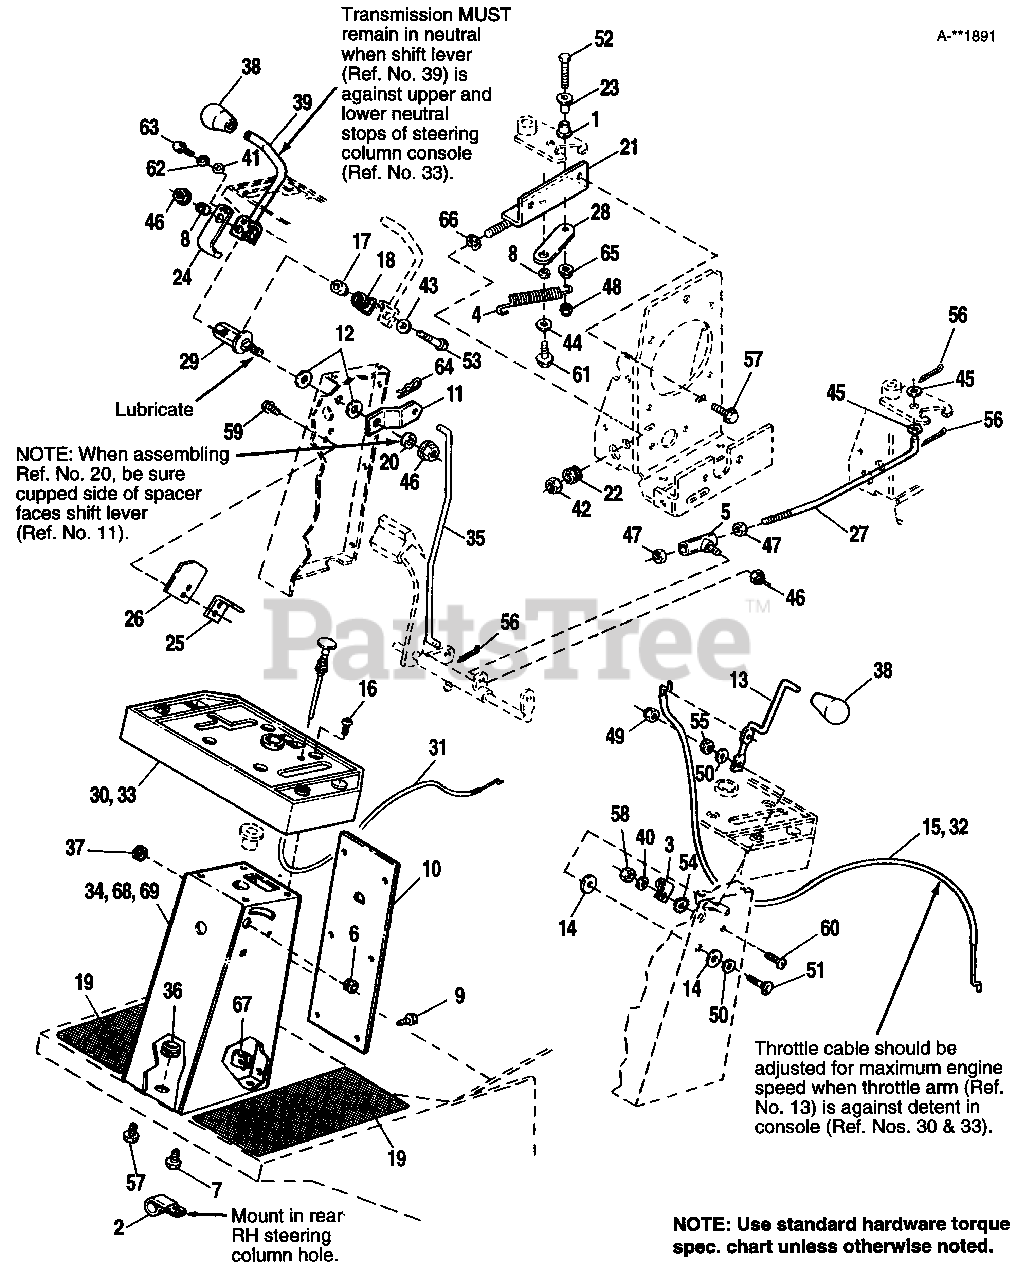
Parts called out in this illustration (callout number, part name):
1	BUSHING, Nylon
4	SPRING, Extension
7	SCREW, Taptite, 5/16-18 x 3/4
9	SCREW, Hex, 1/4-14 x 5/8
10	PANEL, Steering Column
11	LEVER, Shift
12	WASHER, Nylon, 33/64 x 1
13	THROTTLE ARM
14	WASHER, Nylon
15	CABLE, Throttle (12 HP)
16	SCREW, Taptite, 1/4-20 x 3/4
18	SPRING, Torsion
21	BRACKET ASSY., Control
22	NUT, Adjusting
24	NEUTRAL SWITCH ARM
25	BRACKET, Switch
26	FLIPPER SWITCH (Plastic)
27	ROD, Control
28	ARM, Control
29	PIVOT, Shift
30	CONSOLE, Steering Column (12.5 & 16 HP)
31	CABLE, (12.5 HP & 16 HP Only)
32	CABLE, Throttle (12.5 & 16 HP)
33	CONSOLE, Steering Column (12 HP)
34	STEERING COLUMN ASSY., Orange
35	ROD, Control, Vertical
38	KNOB, Control
39	ROD ASSY., Shift
41	WASHER, Plain, #5
42	NUT, Hex, Jam, 3/8-24
43	WASHER, 5/16
44	WASHER, Plain
45	WASHER, Plain, 5/16
46	NUT, Hex, ESNA Lock, 5/16-18
47	NUT, Hex, 5/16-24
48	NUT, Hex, ESNA Lock, 1/4-20
49	NUT, Hex, ESNA Lock, 1/4-20
50	WASHER, Flat, 1/4
51	CAPSCREW, Hex, 1/4-20 x 1
52	CAPSCREW, Hex, 1/4-20 x 1-3/4
53	CAPSCREW, Hex Head 5/16-18 x 2 G5
54	LOCKWASHER, Ext. Tooth, #10
55	NUT, Hex, 1/4-20
56	PIN, Cotter
57	SCREW, Taptite, 5/16-18 x 1/2
58	NUT, #10-32
59	SCREW, Taptite, #10-32 x 3/8
60	SCREW, Rd. Hd., #10-32 x 1/2
61	SCREW, Taptite, 5/16-18 x 5/8
63	SCREW, Taptite, #5-40 x 3/4
64	PIN, Quick
65	NUT, Hex, Whizlock, 1/4-20
67	SPEED NUT, "U" Type #14
68	STEERING COLUMN ASSY., Red
69	STEERING COLUMN ASSY., Green
